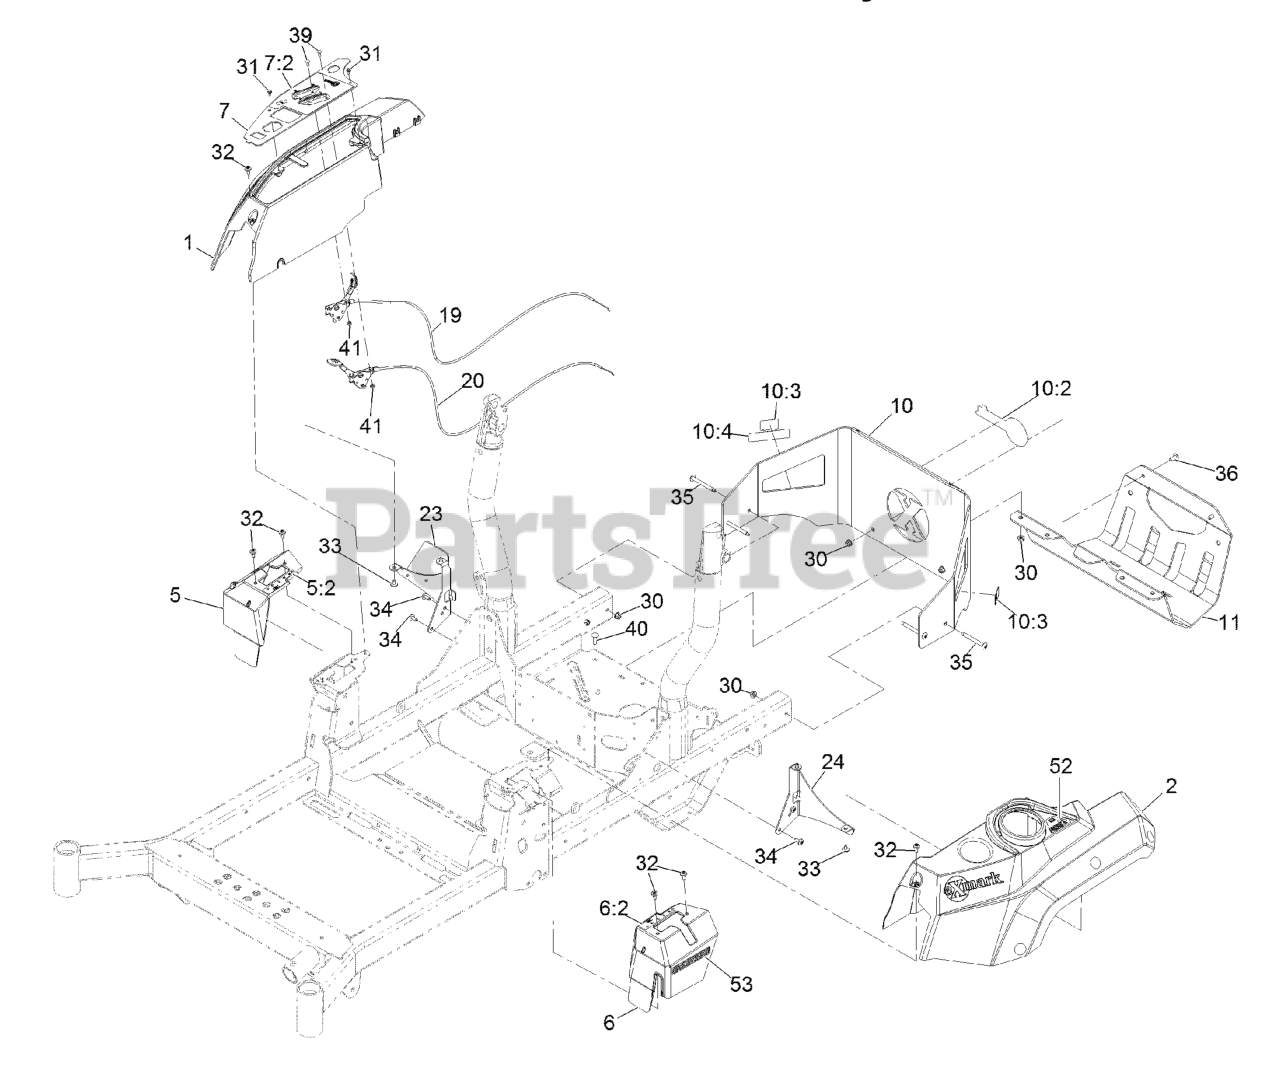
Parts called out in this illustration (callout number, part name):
1	CONSOLE, RH
2	CONSOLE, LH
5	COVER-CONTROL, MOTION (RH
5:2	Decal-Control, Motion (RH)
6	COVER-CONTROL, MOTION (LH
6:2	Decal-Control, Motion (LH)
7	CTRL PANEL ASM W/DECAL
7:2	DECAL-CONTROL PANEL
10	REAR GUARD ASM
10:2	DECAL-EXMARK LOGO
10:3	DECAL-WARNING
10:4	DECAL-ARRESTOR, SPARK
11	GUARD-MUFFLER
19	CABLE-CONTROL, CHOKE
20	CABLE-CONTROL, THROTTLE
23	SUPPORT-CONSOLE, RH
24	BRACKET-CONSOLE, LH
30	NUT-HF, NI
31	SCREW-HWH
32	SCREW-SHOULDER
33	SCREW-TORX
34	SCREW-TORX
35	SCREW-TORX
36	SCREW-TORX
39	BOLT-CARR
40	SCREW-CARR
41	NUT-LOCK, NI
52	DECAL-FILL, FUEL
53	DECAL-E-SERIES
